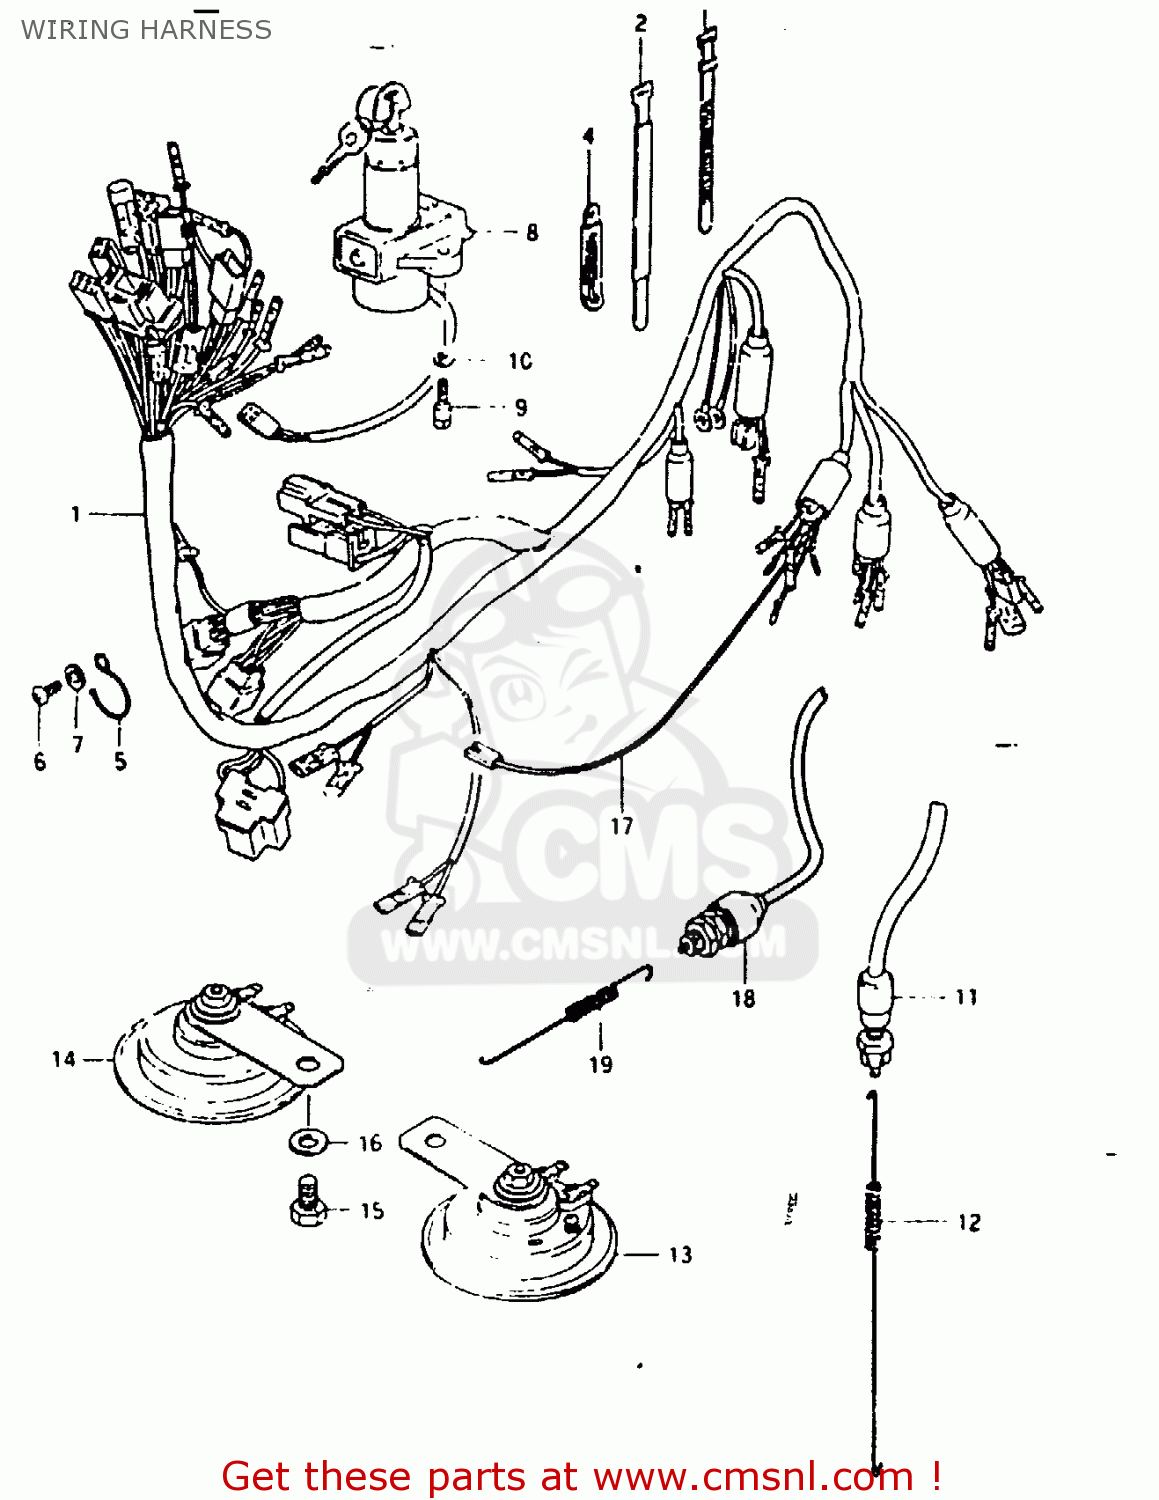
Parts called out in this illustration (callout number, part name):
1	WIRING HARNESS
2	CLAMP
3	CLAMP(L:120)
4	CLAMP
5	GUIDE,WIRING HARNESS
6	SCREW 6X12
7	WASHER
8	LOCK ASSEMBLY,STEERING
9	BOLT
10	LOCK WASHER
11	SWITCH ASSEMBLY,STOP LAMP
12	SPRING
13	HORN ASSY
14	HORN ASSEMBLY,HIGH PITCH
15	BOLT 8X12
16	WASHER
17	WIRE
18	SWITCH ASSEMBLY,SIDE STAND
19	SPRING
